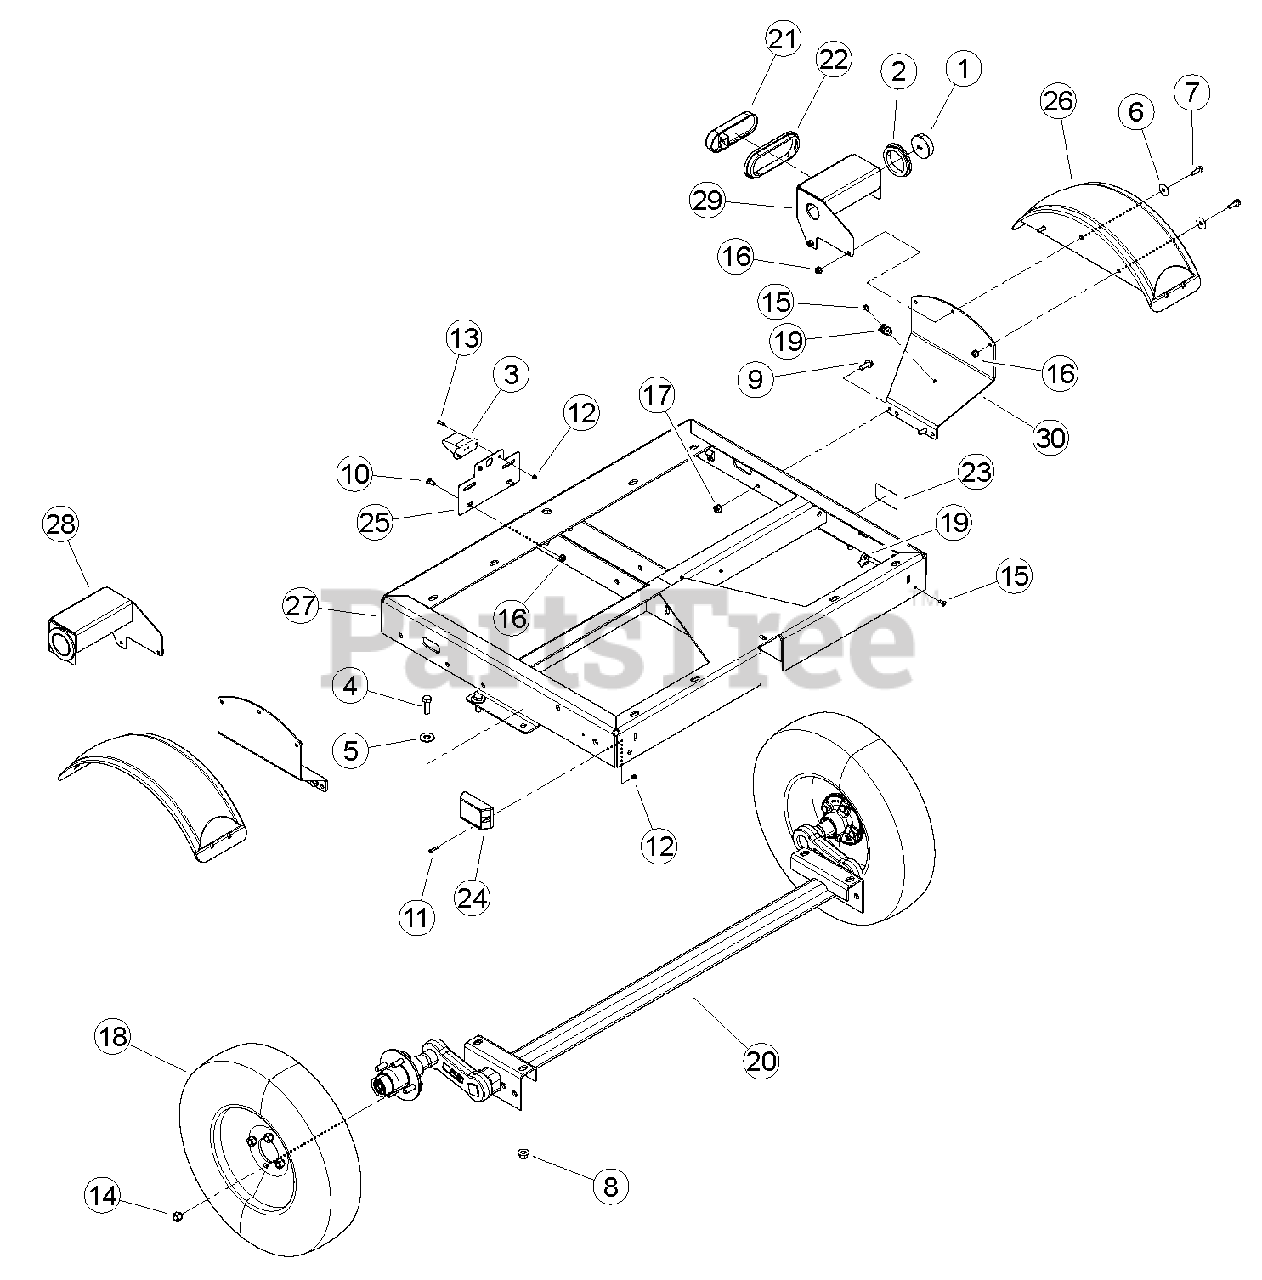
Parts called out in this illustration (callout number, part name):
1	LIGHT, RED CLEARANCE
2	GROMMET, CLEARANCE LIGHT
3	LIGHT, LICENSE PLATE
4	BOLT, 1/2 X 1-1/2 HEX HD GR5 ZP
5	WASHER, 1/2" FLAT ZP
6	WASHER, 5/16" FENDER ZP
7	BOLT, 5/16 X 1 FLANGE NC
8	NUT, 1/2-13 NYLOCK FLANGE
9	BOLT, 3/8 X 1 FLANGE NC
10	BOLT, 5/16 X 3/4 GR5 NC ZP CRG
11	SCREW, MCH 10-24 X 1" RND HD PHL ZP
12	NUT, 10/24 NYLOCK TYPE NM ZP
13	SCREW, MCH 10-24 X 3/4" PAN HD PH ZP
14	NUT, 1/2-20 WHEEL
15	RIVET, AL BLIND 1/4 X 3/4 DOME HEAD
16	NUT, 5/16-18 NYLOCK-FLANGE
17	NUT, 3/8-16 NYLOCK FLANGE
18	ASSEMBLY, 5.30-12 TIRE + SPOKE RIM
19	CLAMP, CABLE MOUNT
20	AXLE, 2000 LB TORSION
21	TAIL LIGHT, OVAL LED
22	GROMMET, OVAL TAIL LIGHT
23	DECAL, 5.30-12 LOAD RATING
24	LIGHT, AMBER MARKER
25	PLATE, LICENSE
26	FENDER, BLACK PLASTIC DRILLED
27	WELDMENT, TRAILER BASE
28	BRACKET, LIGHT RH
29	BRACKET, LIGHT LH
30	MOUNT, FENDER
